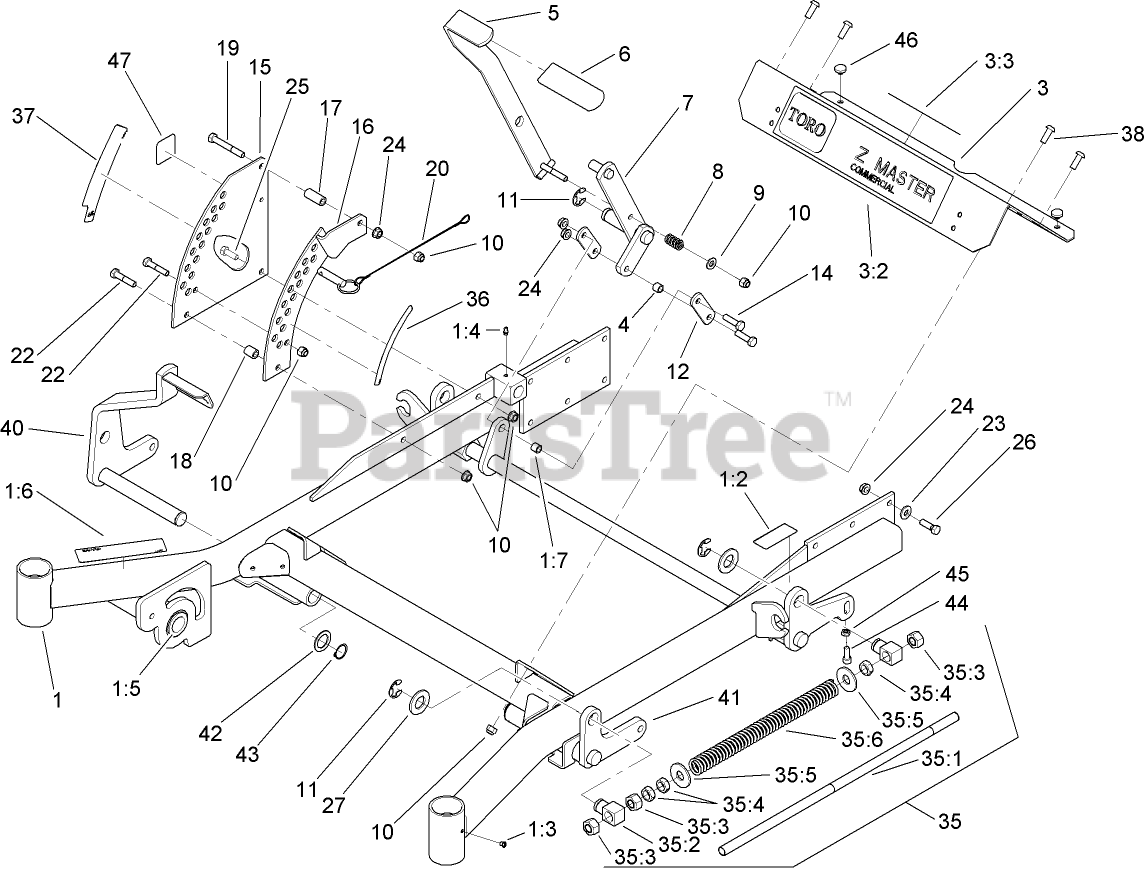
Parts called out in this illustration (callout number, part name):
1	FRAME ASM
1:2	DECAL-BRAKE, PARKING
1:4	FITTING-GREASE
1:5	BUSHING
1:6	DECAL-WARNING
1:7	Bushing
3	FOOTREST
3:3	DECAL-DANGER, SLOPE
4	Bushing
5	LEVER-LIFT
6	GRIP-LEVER, LIFT
7	ARM-LIFT, DECK
8	SPRING-COMPRESSION
9	WASHER-FLAT
10	NUT-LOCK, NI
11	RING-RETAINING, EXT
12	ARM-LIFT, DECK
14	SCREW-HH
15	PLATE-LIFT, DECK
16	PLATE-LIFT, DECK
17	BUSHING-LEVER, LIFT
18	BUSHING-LEVER, LIFT
19	SCREW-HH
20	Hitch Pin ASM
22	SCREW-HH
23	WASHER-BELLEVILLE
24	NUT-HHF, WHIZ
25	SCREW-HH
26	SCREW-HH
27	WASHER-FLAT
35	Front Frame Spring ASM
35:1	ROD-LIFT, DECK
35:2	SWIVEL-DECK MOUNT, REAR
35:3	NUT-HEX
35:4	NUT-JAM
35:5	WASHER-FLAT
35:6	SPRING-SUPPORT, DECK
36	DECAL-HEIGHT, DECK
37	DECAL-HEIGHT, DECK
38	SCREW-HSBH
40	LIFT-DECK, RH FRONT
41	LIFT-DECK, LH
42	WASHER-SPACER
43	RING-RETAINING
44	SCREW-HSH
45	NUT-JAM
46	BUMPER
47	DECAL-NOISE
